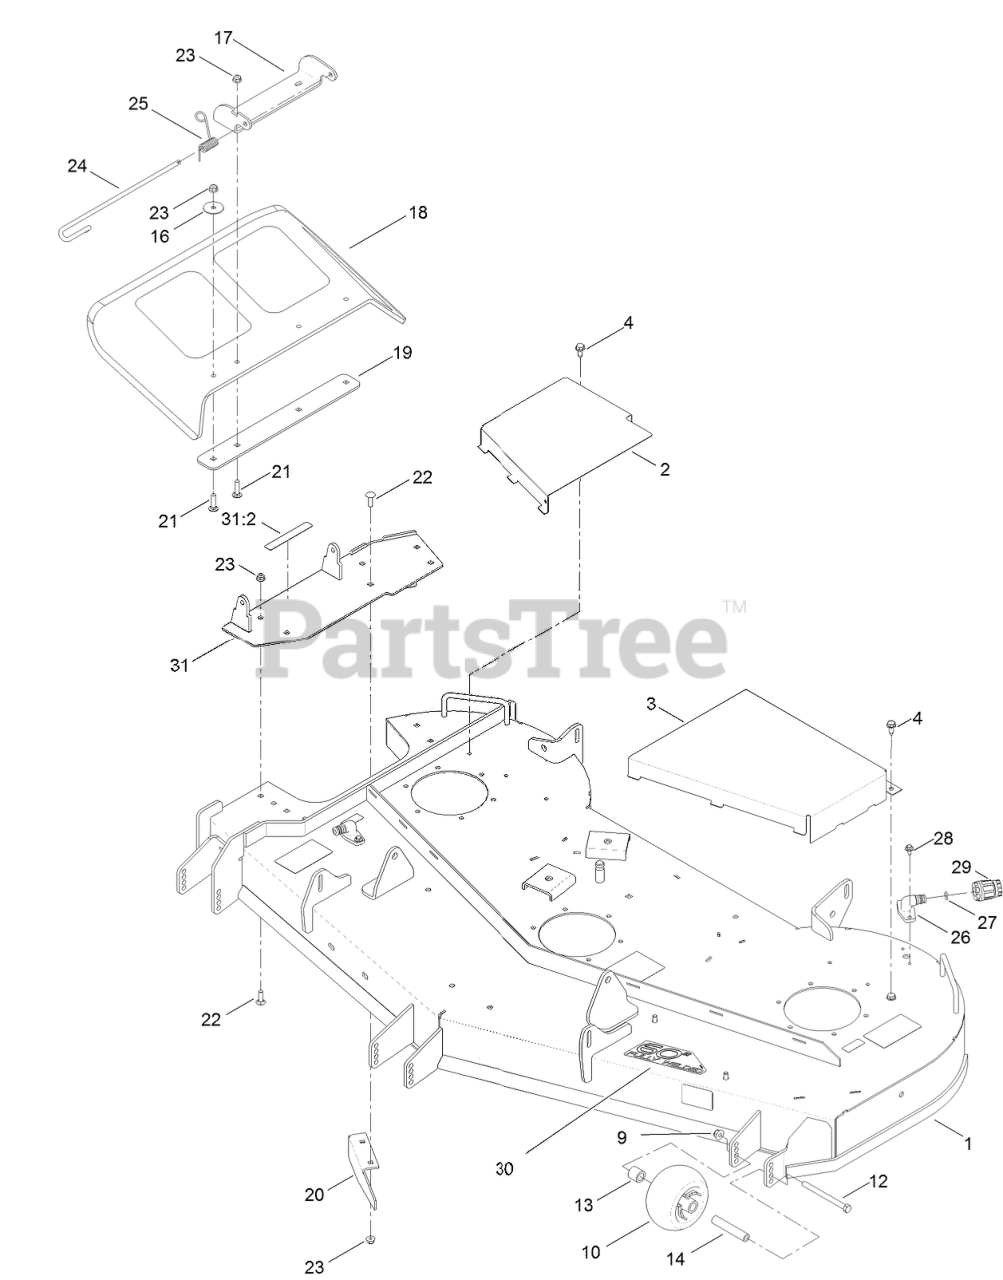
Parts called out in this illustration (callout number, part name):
1	60 INCH DECK ASM
2	COVER-BELT, RH
3	COVER-BELT, LH
4	SCREW-HWHTF
9	NUT-HF, NI
10	ROLLER-SCALP, ANTI
12	SCREW-HH
13	SPACER-AXLE, REAR
14	TUBE-SPANNER
16	WASHER-FLAT
17	BRACKET-DEFLECTOR, UPPER
18	DEFLECTOR
19	PLATE-DEFLECTOR
20	BAFFLE-CUTOFF
21	SCREW-CARR
22	SCREW-CARR
23	NUT-HF, NI
24	PIN-CHUTE
25	SPRING-TORSION
27	O-RING
28	SCREW-HHFTF
29	CONNECTOR-HOSE
31	PIVOT-DEFLECTOR
31:2	DECAL-DANGER
